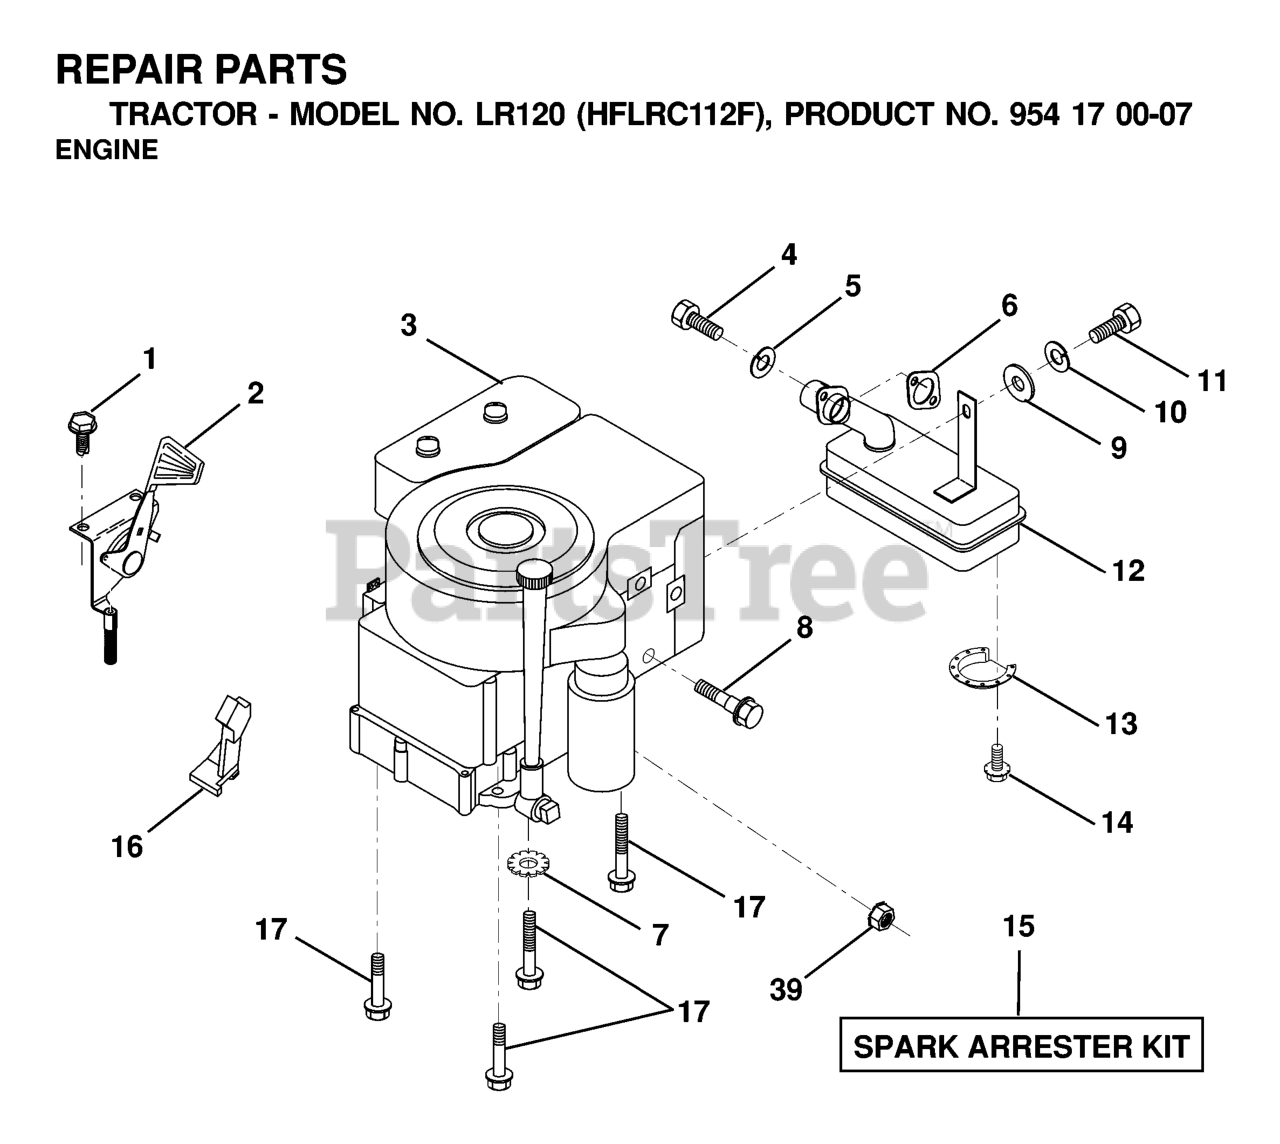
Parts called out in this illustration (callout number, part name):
1	SCREW LT
2	CONTROL.TH/CH.RH.BLK.FLG.EEC
4	SCREW
5	WASHER.LOCK.HVY.HLCL.SPR.5/16
6	REPL BY 532 27 22-93
7	LOCKWASHER
9	WASHER
10	LOCKWASHER
12	MUFFLER.SINGLE.B&S.12HP
13	DEFL MUFFLER LTV
14	SCREW
15	KIT.SPARK ARRESTOR 794945 B&S
16	STOP THROTTLE
17	SCREW LT
39	NUT FLANGE 1/4-20 STARTER NUT
